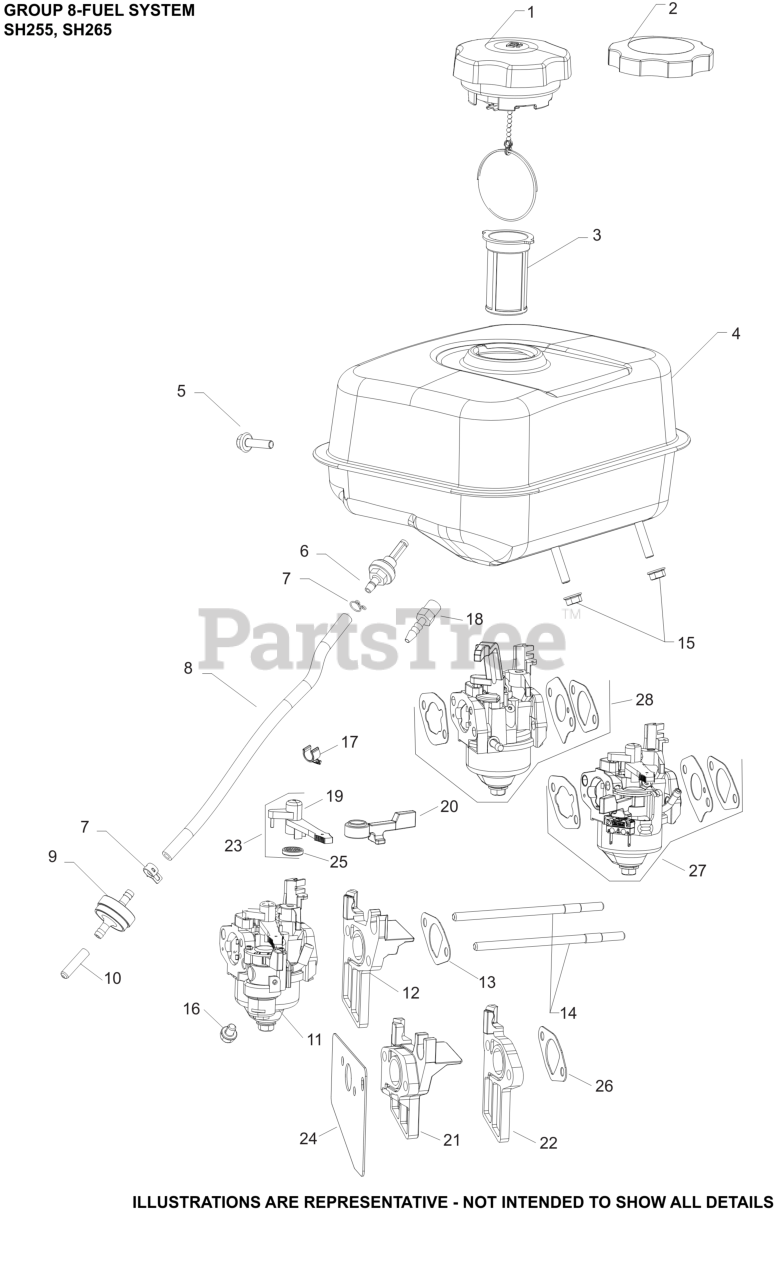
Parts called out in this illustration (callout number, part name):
1	FUEL CAP, ASSEMBLY-USE 17 173 49-S
3	FILTER, FUEL TANK
4	KIT, FUEL TANK
5	SCREW, HEX SOCKET HEAD CAP
6	FITTING, FUEL ASSY
7	CLAMP, FUEL LINE
8	LINE, FUEL (10"-CUT TO LENGTH)
11	KIT,CARB (HUAYI)
13	KIT, INTAKE GASKET
14	STUD, CARBURETOR
15	NUT, HEX FLANGE (M6) - USE 14 100 16-S
17	CLIP, FUEL HOSE
22	INSULATOR, CARBURETOR
NI	KIT, CARBURETOR REPAIR (HUAYI)
NI	KIT, HIGH ALT (4000-8000 FT)
NI	KIT, HIGH ALTITUDE ABOVE 8000'
